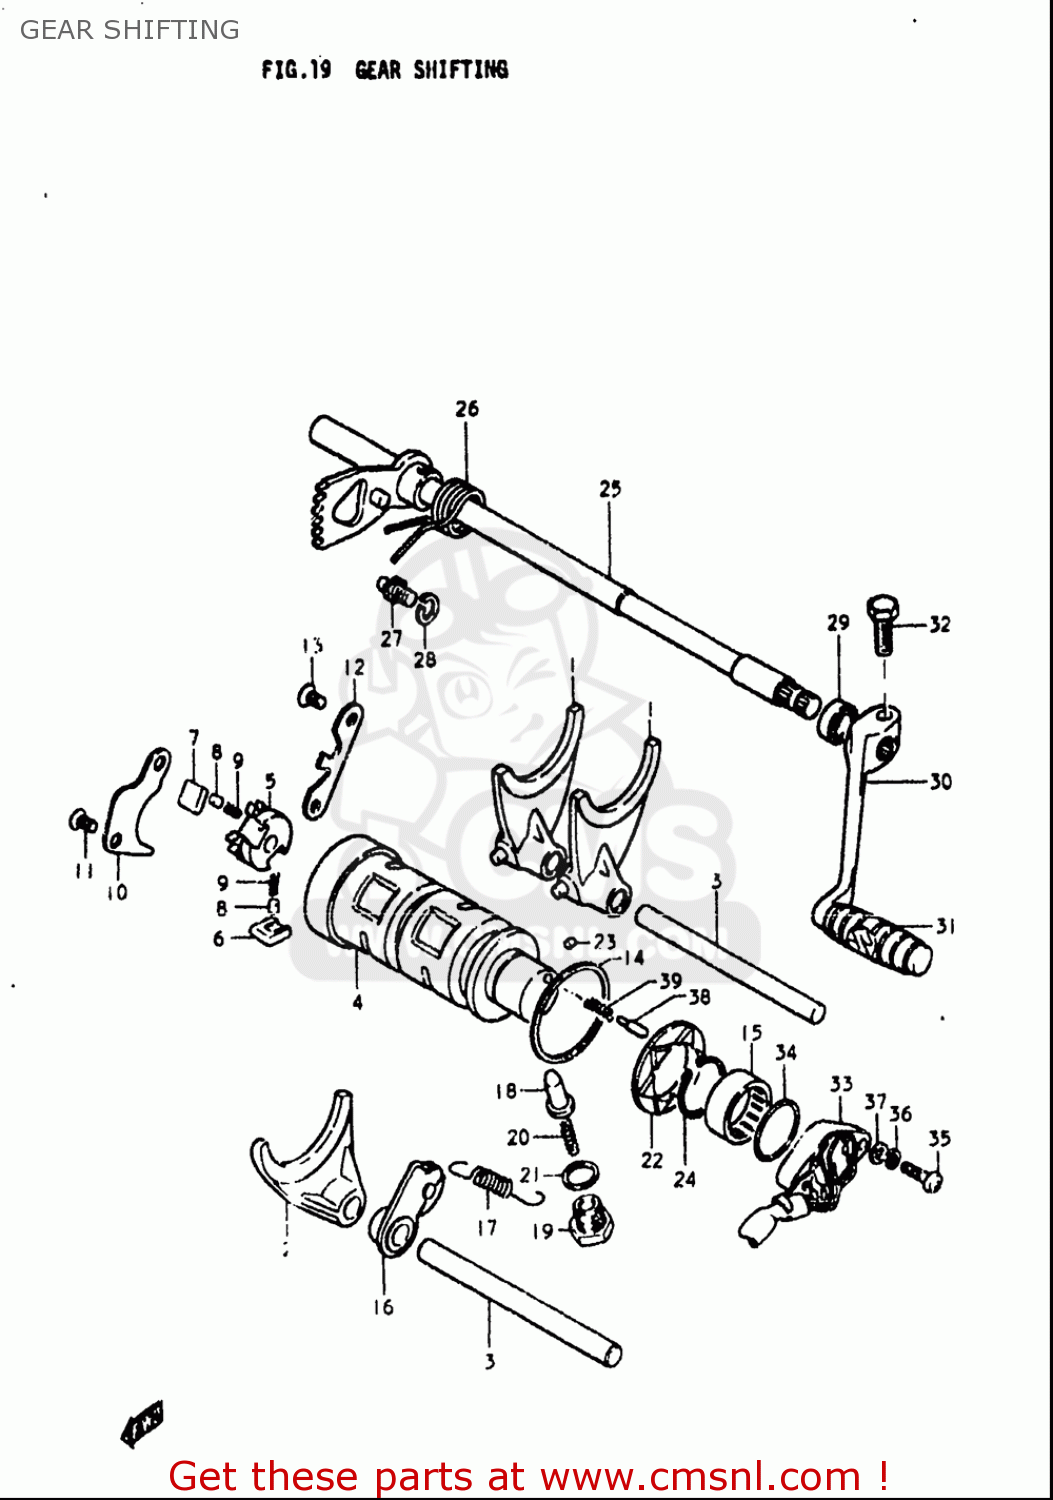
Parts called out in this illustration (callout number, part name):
1	FORK,GEAR SHIFT NO.1
2	FORK,GEAR SHIFT NO.3
3	SHAFT,GEAR SHIFT FORK
5	GEAR,GEAR SHIFT CAM DRIVEN
6	PAWL,GEAR SHIFT NO.1
7	PAWL,GEAR SHIFT NO.2
8	PIN(5X8)
9	SPRING
10	LIFTER,GEAR SHIFT PAWL
11	SCREW
12	GUIDE,GEAR SHIFT CAM
13	SCREW
14	WASHER(40X45X1)
15	BEARING(25X32X12)
16	STOPPER,GEAR SHIFT CAM
17	SPRING
18	STOPPER,GEAR SHIFT CAM NO.2
19	HOLDER,GEAR SHIFT CAM STOP SPR
20	SPRING
21	GASKET(14X19.2X2) (NAS)
22	PLATE,GEAR SHIFT CAM STOPPER
23	PIN
24	CIRCLIP
26	SPRING
27	STOPPER,GEAR SHIFT ARM
28	WASHER,LOCK
29	SEAL,OIL (12X22X9)
30	LEVER ASSY,GEAR SHIFT
31	RUBBER,GEAR SHIFT PEDAL
32	BOLT
33	TERMINAL BASE ASSY,GEAR SHIFT
34	O RING(D:2.4,ID:26.2)
35	SCREW
36	WASHER,LOCK
37	WASHER
38	PIN(5X15.5)
